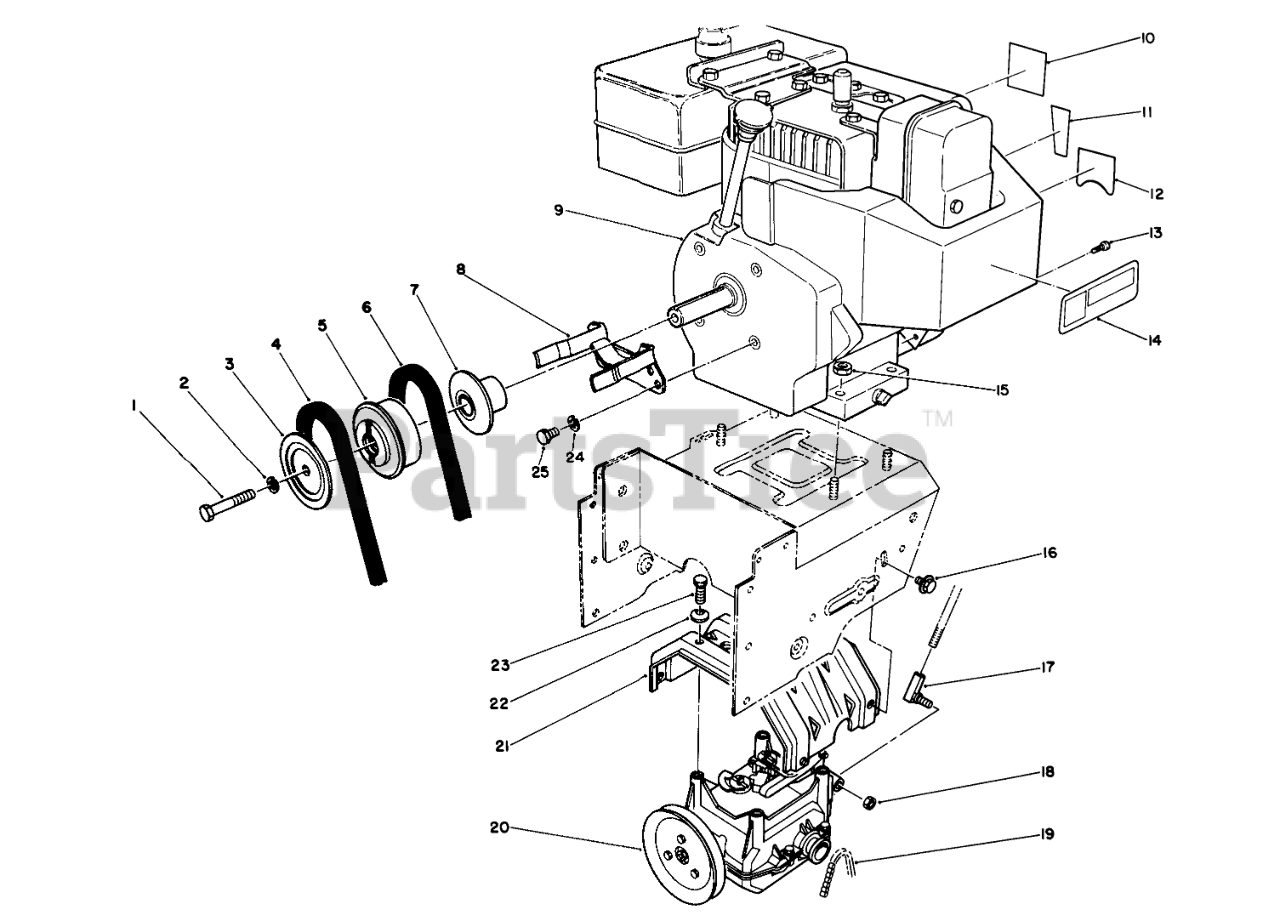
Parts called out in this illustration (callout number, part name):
1	SCREW-HH
2	WASHER-LOCK
3	Sheave Half-Impeller
4	V-BELT
5	LH CASTOR ARM ASM
6	V-BELT-TRACTION
7	TENSION BUSHING
8	Guide-Belt
10	DECAL-PRIMER
11	DECAL-THROTTLE
12	DECAL-CHOKE
13	SCREW-HWH
14	DECAL-HOT SURFACE, WARNING
15	NUT-HF
16	SCREW-HHF
17	JOINT-BALL
18	NUT-LOCK, NI
19	CHAIN
20	TRACTION GEARCASE ASM
21	Frame-Transmission
22	WASHER-SPRING
23	SCREW-HWHTF
24	WASHER-LOCK
25	SCREW-HH
